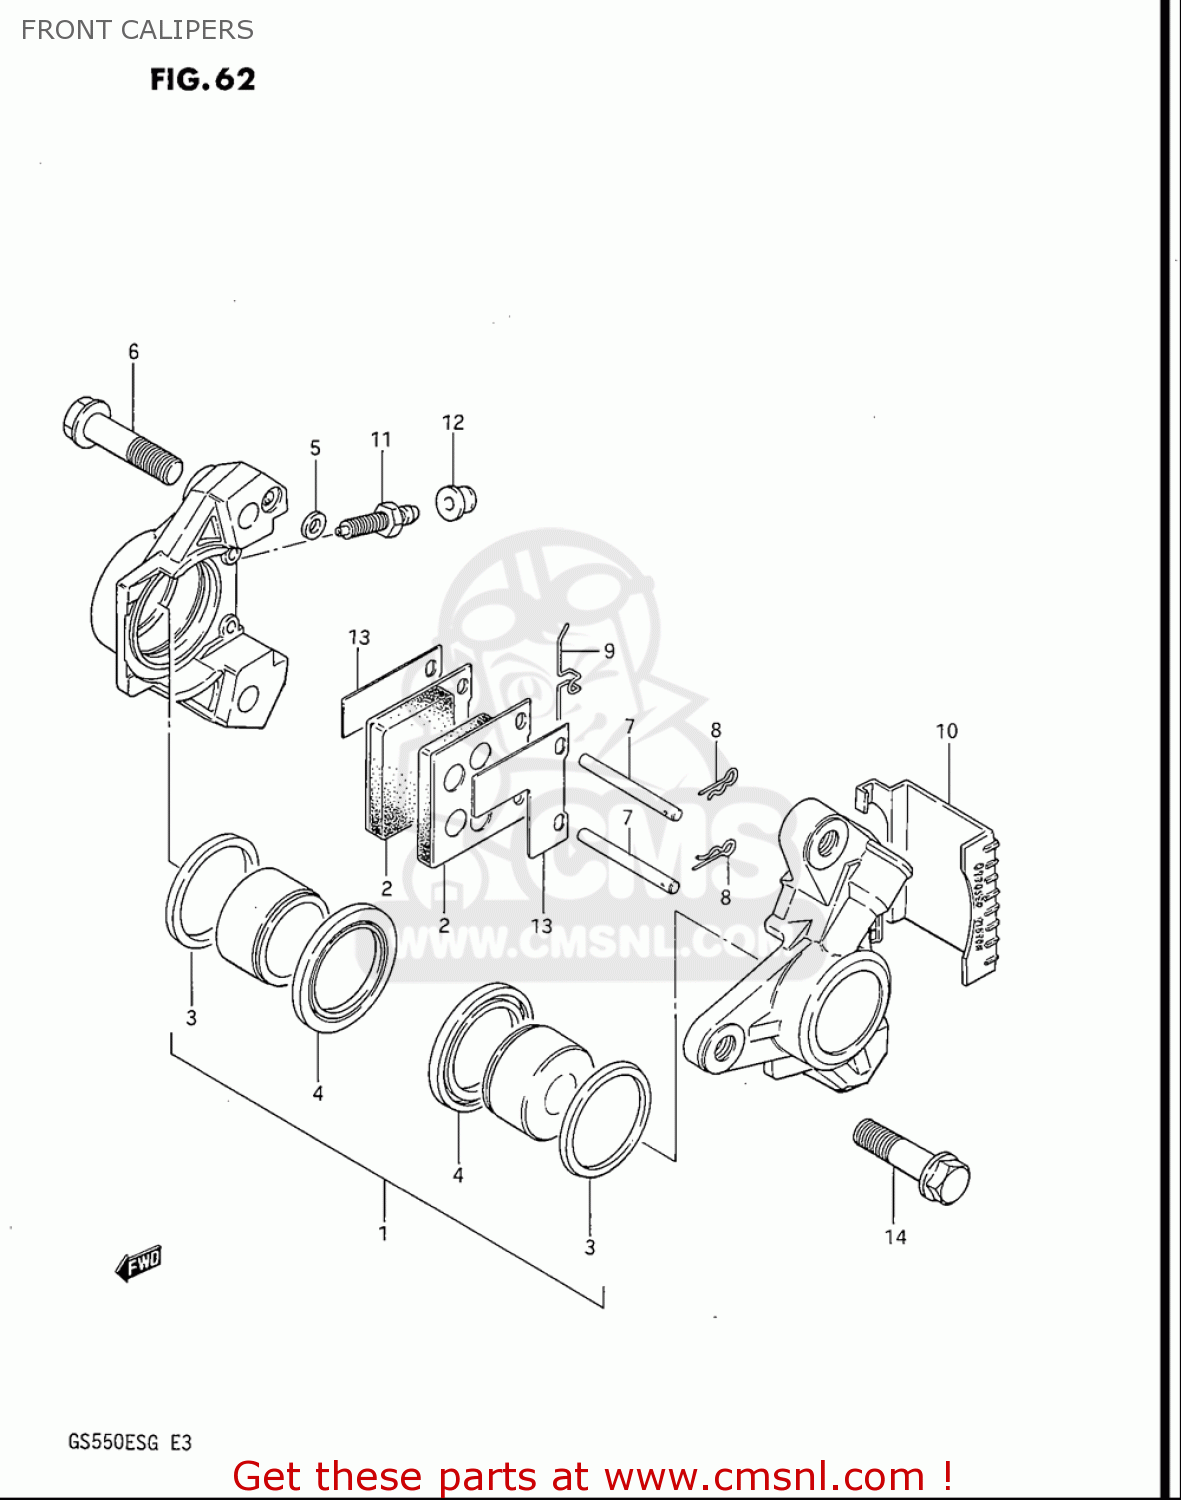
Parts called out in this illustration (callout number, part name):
1	PISTON SET
2	PAD SET
3	SEAL,PISTON
4	BOOT
5	SEAL,JOINT
6	BOLT,HOUSING
7	PIN,PAD
8	CLIP,PAD PIN
9	SPRING
10	COVER
11	BLEEDER
12	CAP,BLEEDER PLUG
13	SHIM
14	BOLT 10X37
